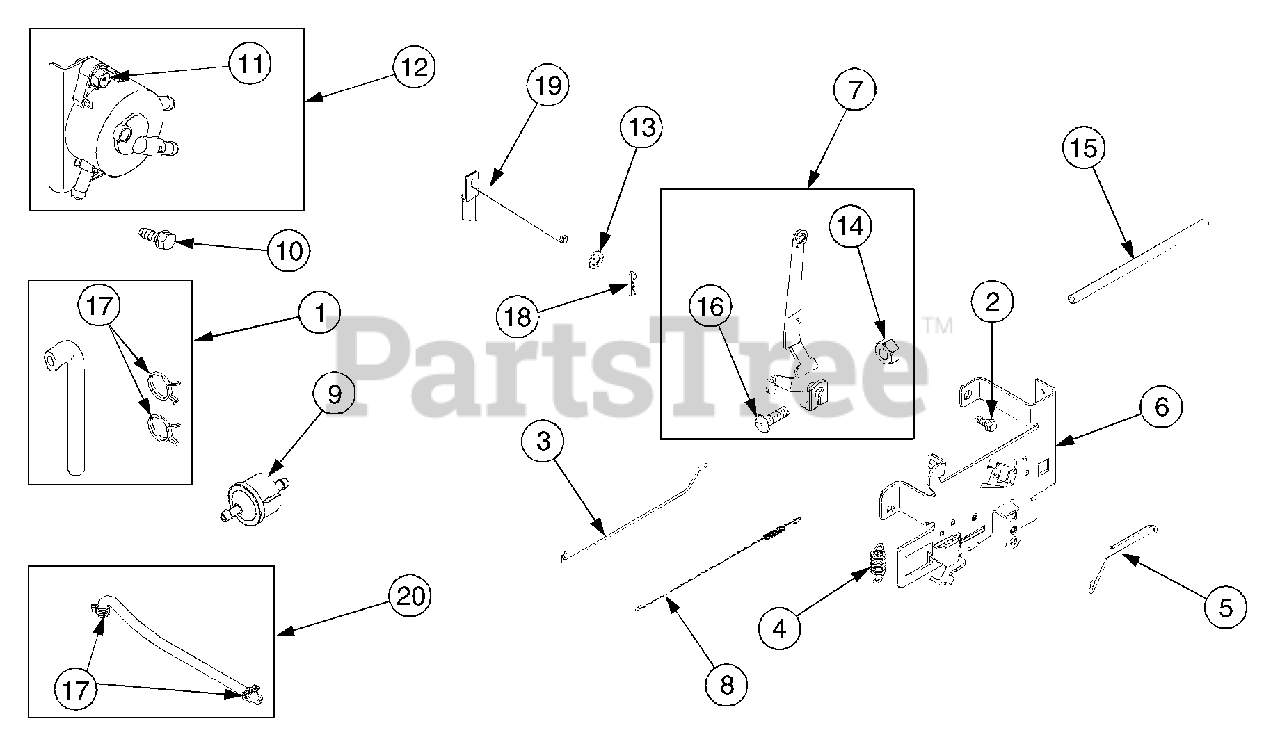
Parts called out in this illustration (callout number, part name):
1	Line, Fuel
2	Screw (Control Bracket)
3	Link, Mechanical Governor
4	Spring, Governor
5	Link, Choke
6	Bracket, Control
7	Control Lever, Governor
8	Spring, Governor Link
9	Filter, Fuel
10	Screw (Fuel Pump)
11	Screw (Fuel Pump)
12	Pump, Fuel
14	Nut (Governor Control Lever)
15	Shield, Cable
16	Bolt (Governor Control Lever)
17	Clamp, Hose
18	Pin, Cotter
19	Crank, Governor
20	Hose, Vacuum
